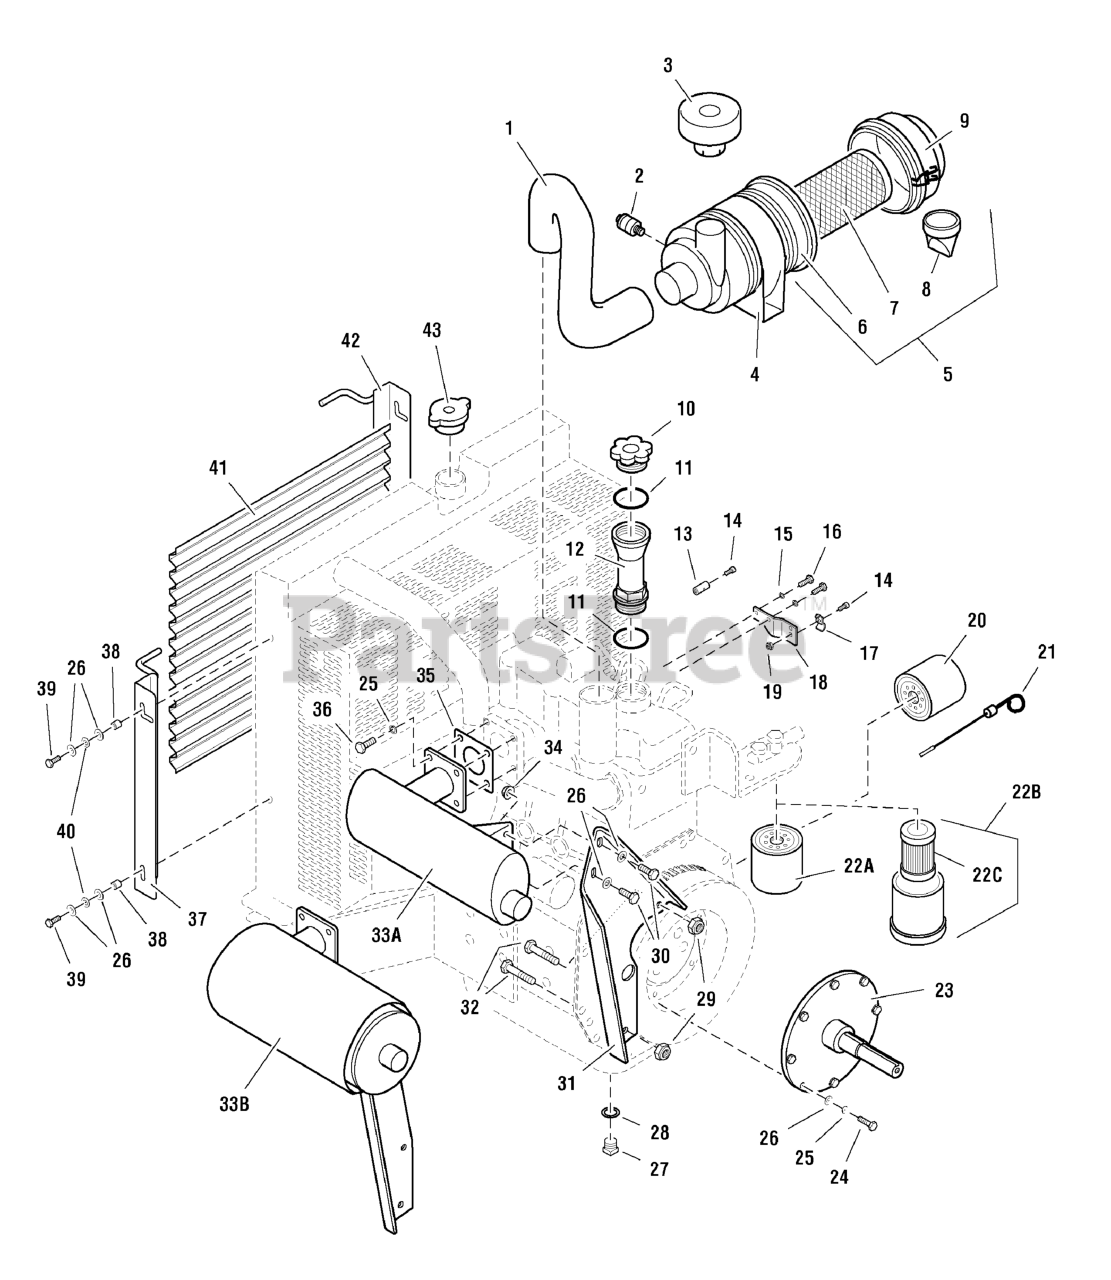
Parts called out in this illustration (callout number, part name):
1	AIR INLET HOSE
1	HOSE CLAMP
2	AIR CLEANER INDICATOR
3	PRE-CLEANER
4	AIR CLEANER BRACKET
5	AIR CLEANER ASSEMBLY, Complete
6	AIR CLEANER HOUSING ASSEMBLY
7	AIR CLEANER ELEMENT
8	AIR CLEANER DUST VALVE
9	AIR CLEANER COVER
10	OIL FILL CAP
11	OIL FILL O-RING SEAL
12	OIL FILL EXTENSION
13	BARREL CLAMP
14	SCREW, #10-24 x 3/4
15	WASHER, 1/4 LOCK
16	BOLT, M6 x 10MM
17	CLAMP
18	THROTTLE BRACKET
19	NUT, #10-24 Hex Nylon Lock
20	OIL FILTER
22A	FUEL FILTER
22B	FUEL FILTER ASSEMBLY, Complete
22C	FILTER ELEMENT
24	BOLT, 5/16-18 x 1-1/4
25	WASHER, 5/16 LOCK CZ
26	WASHER, 5/16" SAE
27	OIL PAN PLUG
28	WASHER, Oil Pan Plug
29	NUT, 3/8-16 HEX NYLON LOCK
30	BOLT, 5/16-18 X 1 GD5 YZ
31	MUFFLER SUPPORT
32	BOLT, 3/8-16 X 1-3/4" GD5 CZ
33A	MUFFLER (Silver)
33B	MUFFLER (Black)
34	NUT, 5/16-18 HEX SERRATED FLANGE (SMALL)
35	GASKET, EXHAUST MANIFOLD - NET
36	BOLT, M8-1.25 X 25MM GR 8.8
37	SCREEN KEEPER-LH
38	BUSHING
39	BOLT, M5 x 12MM
40	WASHER, M8, Wave
42	SCREEN KEEPER-RH
43	PRESSURE CAP
44	FUEL SOLENOID
45	WASHER, Fuel Solenoid
46	WATER PUMP
47	WATER HOSE-UPPER
48	WATER HOSE-LOWER
49	GASKET, Water Pump
50	THERMOSTAT
51	GASKET, Thermostat
52	STARTER MOTOR
53	ALTERNATOR
54	BELT
55	FUEL PUMP,# 295-4070 - NET
56	GASKET, Fuel Pump
57	GLOW PLUG
58	RADIATOR
59	SWITCH, Oil Pressure
60	SWITCH, Water Temperature
61	STARTER SOLENOID
62	SEAL, REAR MAIN - NET
63	SEAL, Front Main
64	INJECTOR ASSEMBLY
65	WASHER, 4-HOLE
66	WASHER, SEALING
67	WASHER, CRUSH
68	ISO MOUNT BRACKET
69	BOTTOM RADIATOR BRACKET
70	TOP RADIATOR BRACKET
71	CLAMP, RADIATOR HOSE
72	GASKETS, VALVE COVER
73	PARTS MANUAL, ENGINE
